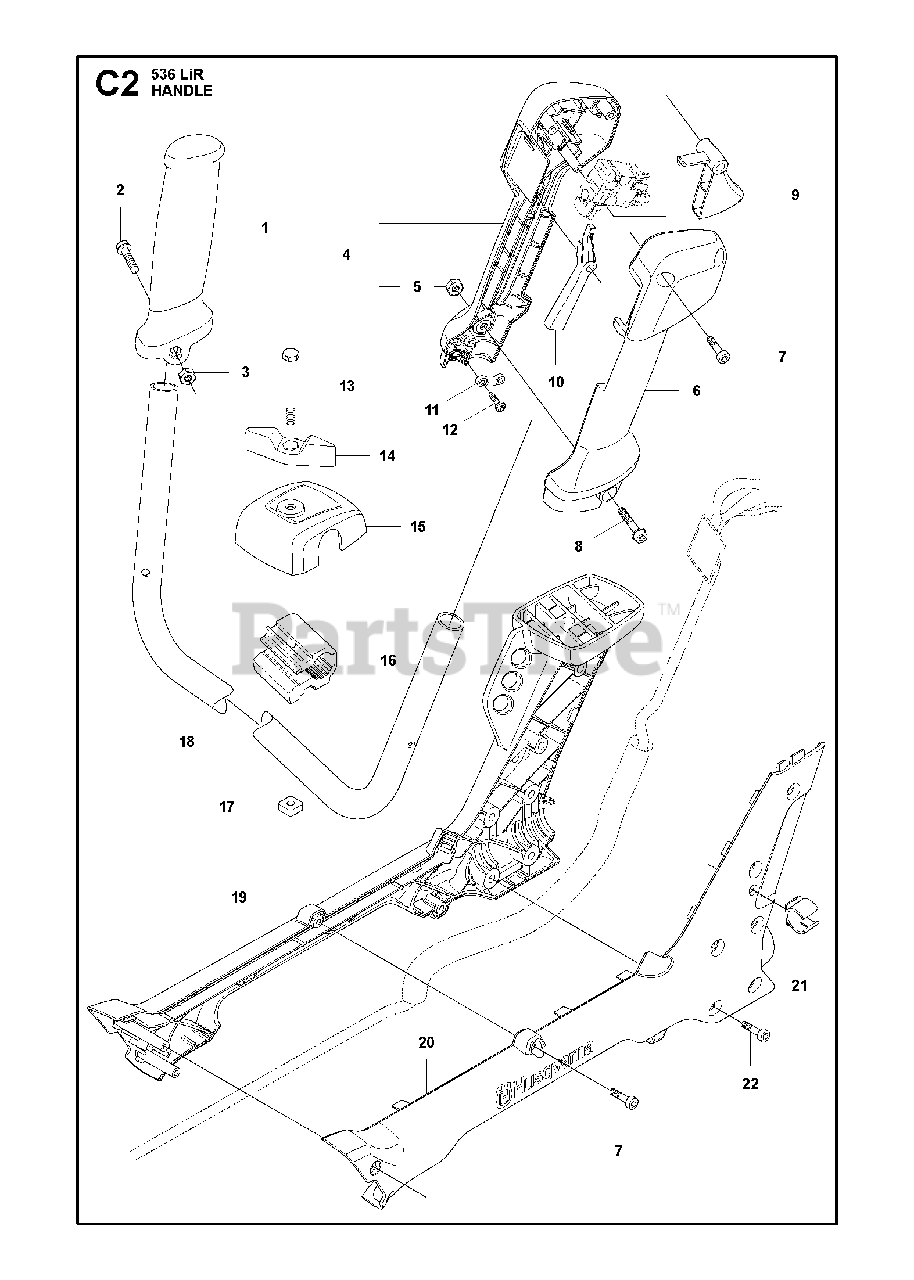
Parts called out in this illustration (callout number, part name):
7	SCREW IHSCT MT4X18 10.9 ZN/FE
8	%SCREW
15	COVER HANDLE BAR
18	HANDLEBAR MACHINED
